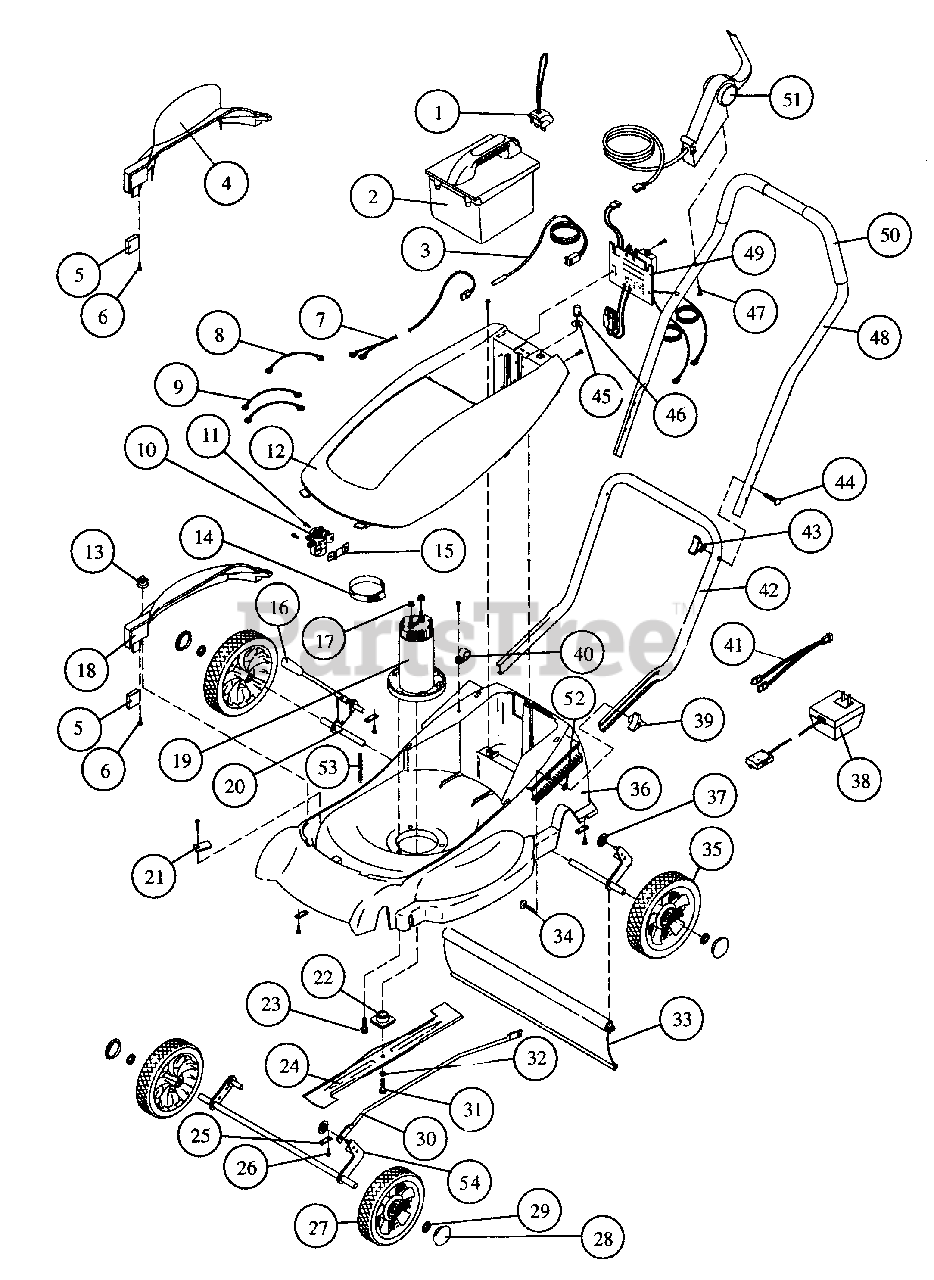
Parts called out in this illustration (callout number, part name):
2	Battery Pack Assembly
3	Interlock Switch Assembly
4	Discharge Chute
7	Circuit Board Wire Assembly
8	Solenoid Wire Assembly
9	Solenoid Wire Assembly
10	Solenoid
11	Regulator Screw
12	Mower Cover
14	Regulator Clamp
15	Regulator Bracket
16	Height Adjustor Handle
17	Motor Nut
18	Mulching Cover
19	Motor
20	Height Adjustor, Rear
21	Retainer
22	Blade Adaptor
23	Bolt, Motor
25	Axle Retainer
27	Front Wheel
29	Retainer
30	Height Adjustor Link
31	Blade Mounting Bolt
32	Washer, Split Ring
33	Drag Shield
34	Lower Handlebar Bolt
35	Rear Wheel
36	Mower Deck
37	Link Retainer
38	Charger
39	Handlebar Knob
40	Wire Clamp
41	Harness, Battery Charger
42	Lower Handlebar
43	Handlebar Knob
44	Handlebar Bolt
45	Circuit Breaker Label
46	Circuit Breaker Boot
47	Handlebar Screw
48	Upper Handlebar
49	Motor Control
50	Foam Grip
51	Deadman Control Assembly
52	Bolt Retainer
53	Chute Stud
54	Height Adjustor (Front)
